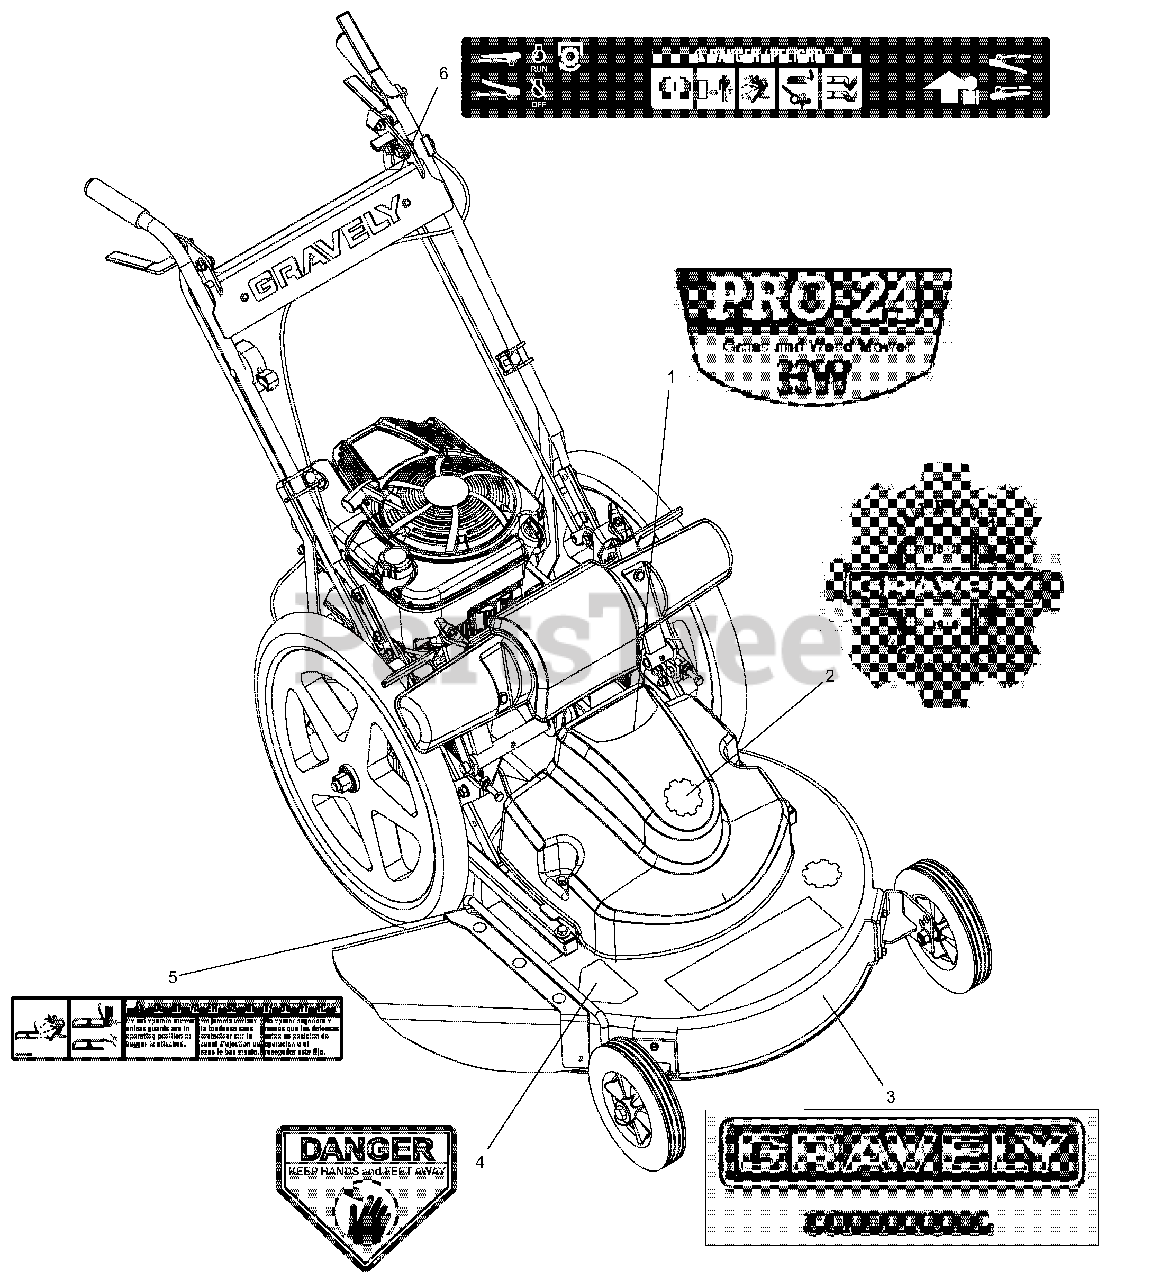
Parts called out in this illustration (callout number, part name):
1	DECAL, PRO -24 HW
2	DECAL, GRAVELY HERITAGE-SMALL
3	DECAL, GRAVELY /COMMERCIAL LOGO
4	DECAL, DANGER
5	DECAL, WARNING
6	DECAL-OPER./DANGER 24HWSP
